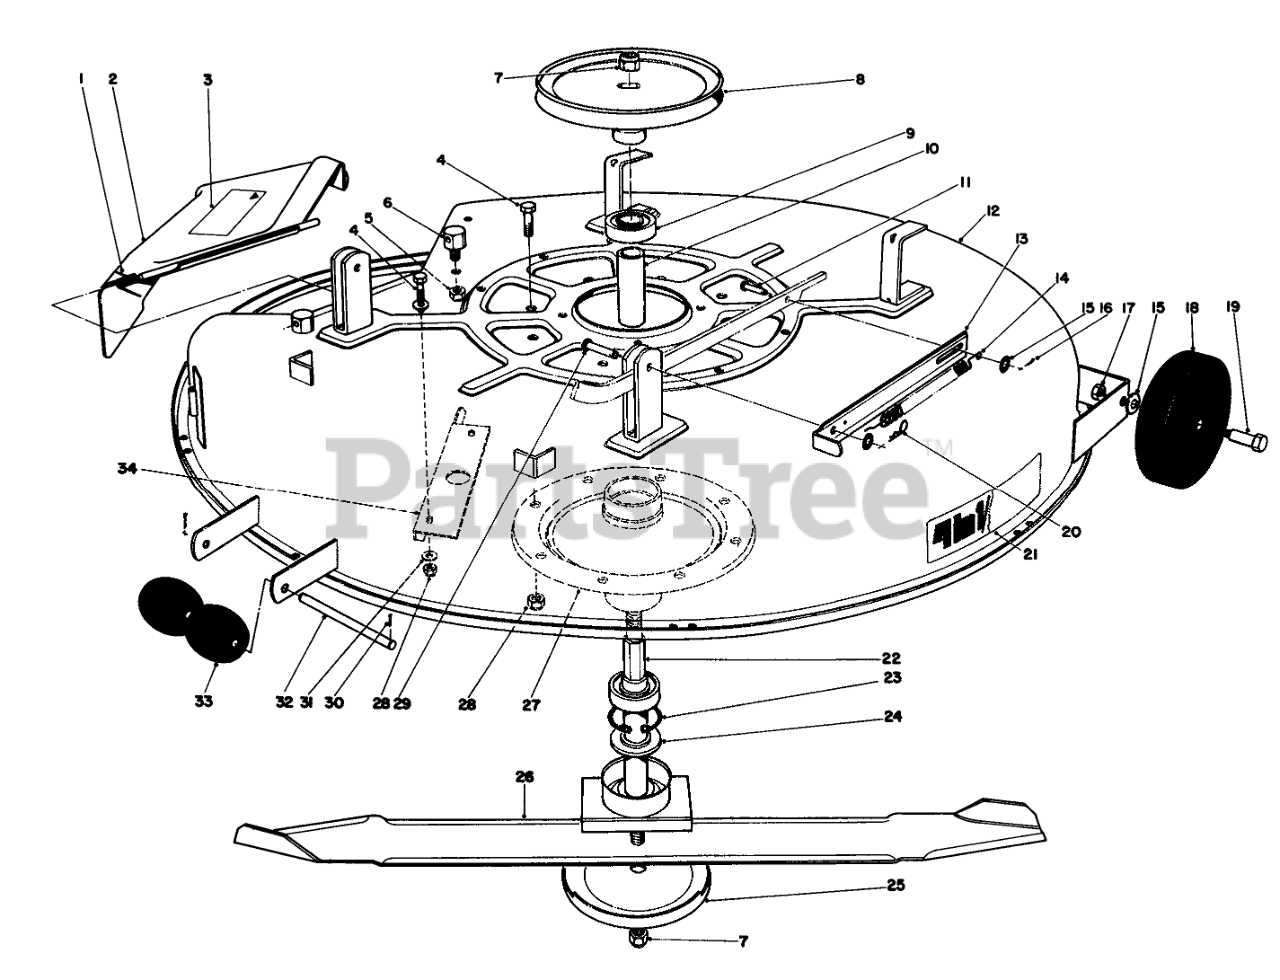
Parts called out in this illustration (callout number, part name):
1	SPRING
2	Deflector Assembly (Incl. Ref. #3)
3	Decal
4	SCREW-HH
5	NUT-LOCK, SIDE
6	POST-PIVOT
8	PULLEY(BLADE DRIVE)
9	BEARING-BALL
10	Spacer-Bearing
11	PIN-CLEVIS
12	Cutter Deck
13	DECK SPRING STRAP R
14	DECK TENSION SPRNG O
15	WASHER-FLAT
16	PIN-COTTER
17	Nut
18	DECK WHEEL
20	PIN-COTTER
21	DECK DECAL
22	SPINDLE SHAFT WA
23	RING-RETAINING
24	SPACER-SPINDLE
25	Cup
26	Blade
27	Spindle Body
28	NUT-LOCK, NI
29	PIN-CLEVIS
30	PIN-COTTER
31	WASHER-PLAIN
32	ROLLER SHAFT
33	ROLLER
34	Baffle Deck
